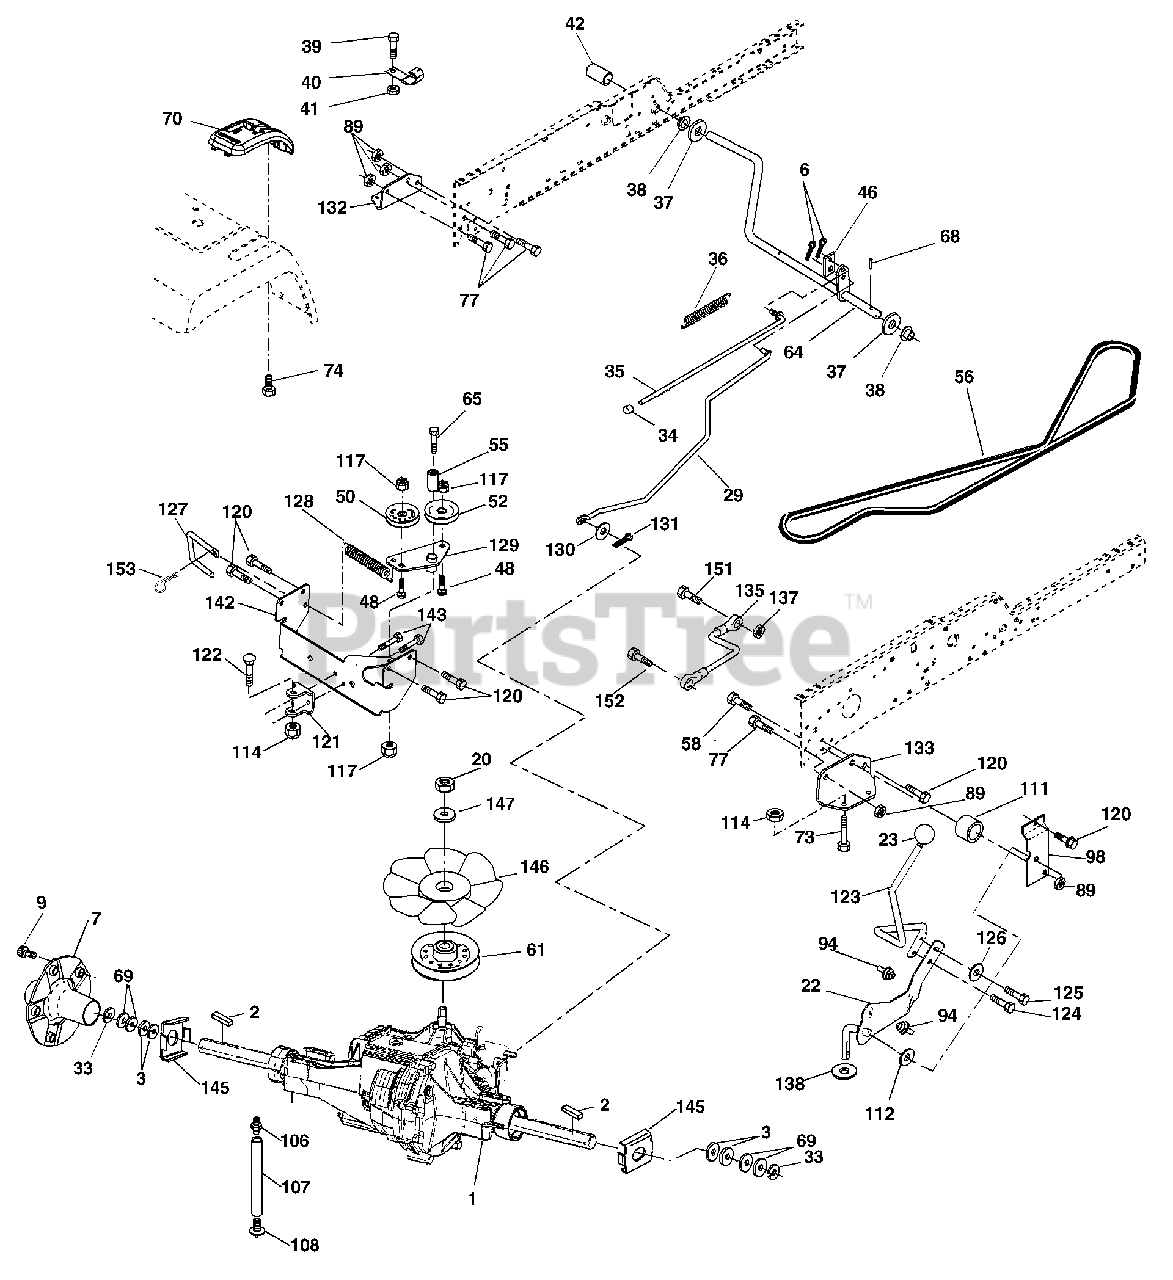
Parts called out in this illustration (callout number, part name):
2	Key 1/4 x 2.5
3	Washer Thrust
6	Pin, Cotter
7	Wheel, Hub Assembly
9	Bolt, Hub
20	Nut
22	Lever Asm Shift Lower
23	Knob
29	Brake, Rod
33	Ring E
34	Cap, Parking Brake
35	Rod, Parking Brake
36	Spring, Drive Ground
37	Washer 25/32 x 1-1/4 x 16 Ga.
38	Nyliner
39	Screw, Fin. #10-24 x 1
40	Actuator, Interlock Switch
41	Nut Centerlock 10-24 unc
42	Cover, Pedal
46	Retainer, Spring
48	Bolt, 3/8-16 x 1-3/4 Gr. 5
50	Pulley, Idler, Flat
52	Pulley, Idler, Grooved
55	Bearing, Idler
56	V-Belt
58	Bolt Fin Hex 7/16-14 x 1-1/2
61	Pulley, Transaxle
64	Shaft, Clutch/Brake Pedal
65	Bolt, Shoulder
68	Pin, Roll
69	Washer
70	Console Automatic YT/GT
73	Bolt Hex Flghd 5/16-18 x 3 Gr. 5
74	Screw Hex Wsh. Hi-Lo 1/4-1/2
77	Bolt Hex 7/16-14 x 1Gr. 5
89	Nut Crownlock 7/16-14 unc
94	Fastener Christmas Tree
98	Bracket Shift
106	O-Ring Asm Hydro Gear
107	Line Fuel Hydro 15" VGT
108	Cap Asm Vent Hydro Gear 70109
111	Spacer Shift Lever VGTH
112	Washer Nylon High Temp
114	Nut Lock Hx W/Ins 5/16-18 unc
117	Nut, Lock Flg. 3/8-16
120	Screw 3/8-16 x .75
121	Bracket Strap Torque
122	Bolt RDHD SQ 5/16-18 unc x 2-1/2
123	Rod Shift
124	Bolt Shoulder 5/16-18 x .561
125	Screw 5/16-18 x 5/8
126	Washer SRRTD 5/16ID x 1.0 x .125
127	Link Control Clutch
128	Spring Drive GRND
129	Bracket Asm Idler Tensioning
130	Washer 13/32 x 5/8 x 16 Ga.
131	Pin Cotter 3/32 x 3/4
132	Bracket Mtg Hydro 3500 LH VGT
133	Bracket Mtg Hydro 3500 RH VGT
135	Link Asm Control Hydro 3500
137	Nut Lock 5/16-18 NC Thd
138	Washer Thrust 5/8 x 1.10 x 1/32
142	Strap Torque HG-3500
143	Screw Thdrol 5/16-18 x 3/4
145	Washer Axle Flange HG-3000
146	Fan 7" Hydro
147	Washer
151	Bolt Fin Hex 5/16-18 x 7/8
152	Bolt Hex 5/16-18 x 1
